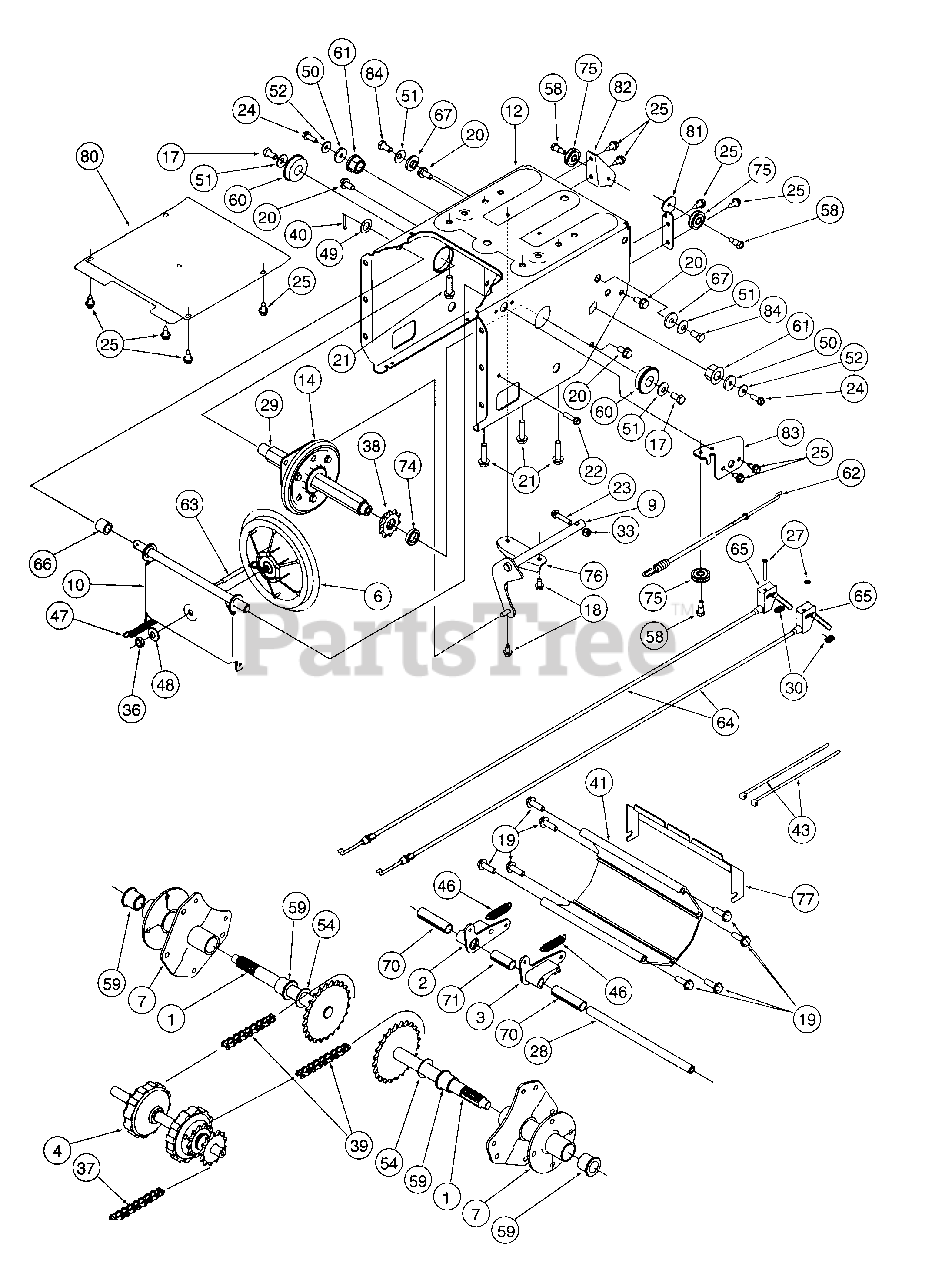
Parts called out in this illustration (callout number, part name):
1	Axle Assembly
2	Dogg Assembly: R.H.
3	Dogg Assembly: L.H.
4	Shift Assembly: Track Drive
14	Friction Wheel Bearing Assembly
17	Hex Lock Screw 5/16-18 x .625 Grade 5
18	Hex Washer Hd. TT Screw
19	Hex Washer Hd. TT Screw
20	Hex Washer Hd. TT Screw
21	Hex Washer Hd. TT Screw
22	Hex Washer Screw
23	Hex Washer Screw
24	TT Screw
25	Hex Washer Head AB Screw
27	Oval C-Sunk Screw
28	Actuator Shaft
29	Hex Shaft: Track Drive
30	Flanged Weld Nut #10-24
33	Top Lock Nut 1/4-20
36	Jam Nut 3/8-24
37	Chain Links
38	Sprocket: 10T
39	Chain
40	Cotter Pin
41	Track Housing
43	Cable Tie
46	Extension Spring
47	Extension Spring
48	Bell Washer
49	Flat Washer
50	Flat Washer
51	Bell Washer
52	Bell Washer
54	Flat Washer
58	Shoulder Screw
59	Flange Bearing
60	Ball Bearing
61	Hex Flange Bearing
62	Auger Clutch Cable
63	Drive Clutch Cable
64	Track Steering Cable
65	Trigger Control
66	Spacer
67	Shoulder Spacer
70	Split Spacer
71	Split Spacer
74	Spacer
75	Roller Cable
